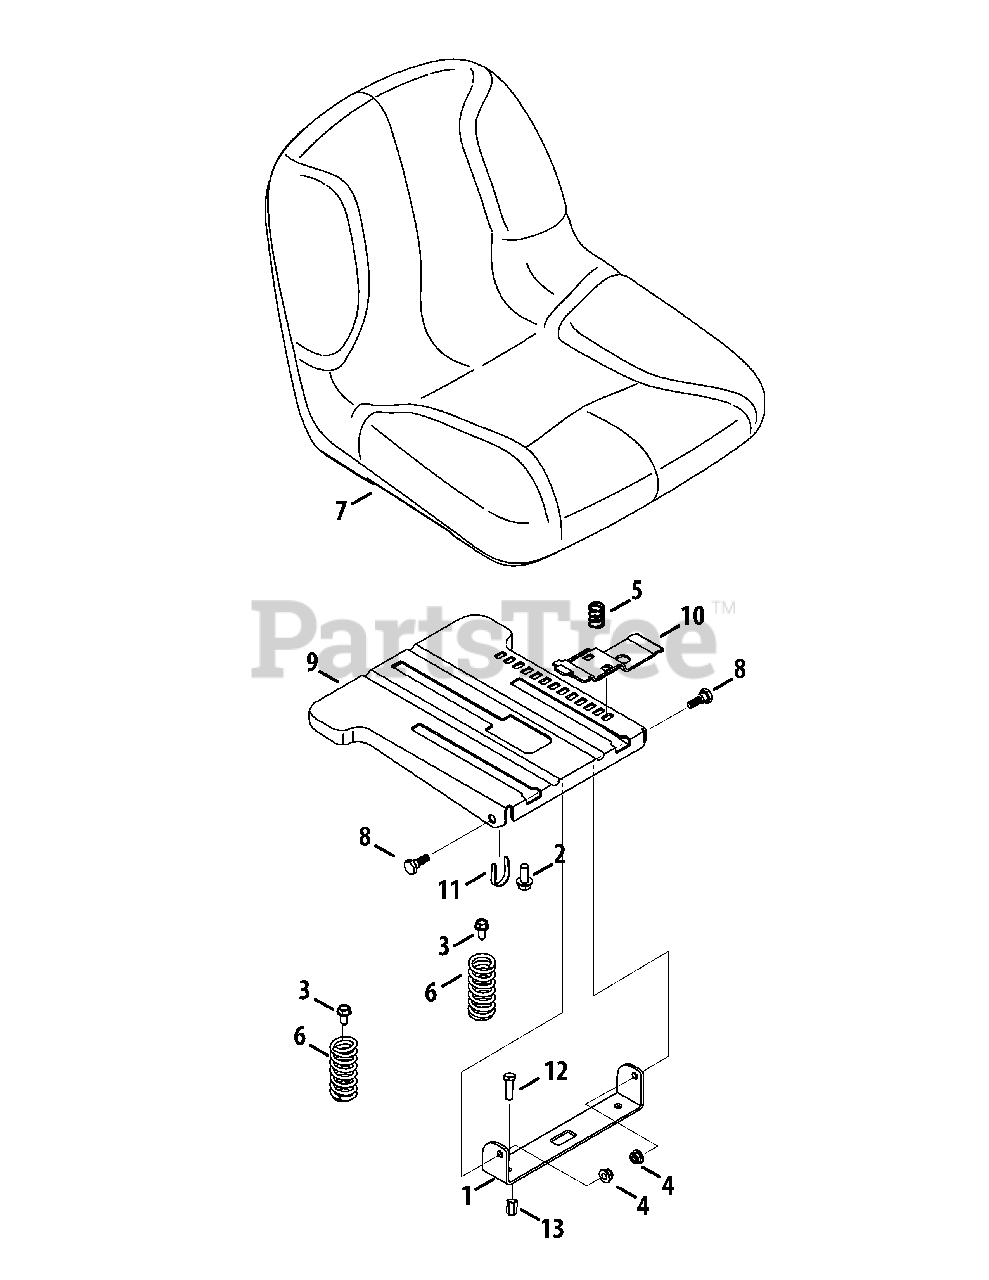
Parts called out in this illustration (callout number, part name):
1	Seat Bracket
2	Hex Flange Bolt 3/8-16 x .875
3	Hex Washer Screw 5/16-18 x .750
4	Flange Lock Nut 5/16-18
5	Compression Spring .68 x 1.065 x .055
6	Compression Spring 1.50 x 3.90 x .200
7	Seat
8	Shoulder Screw 5/16-18 x .437 x .268
9	Seat Mount Bracket
10	Seat Adjustment Lever
12	Hex Hd. Cap Screw 5/16-18 x 1.0 Gr. 5
13	Rivet Nut 5/16-18
